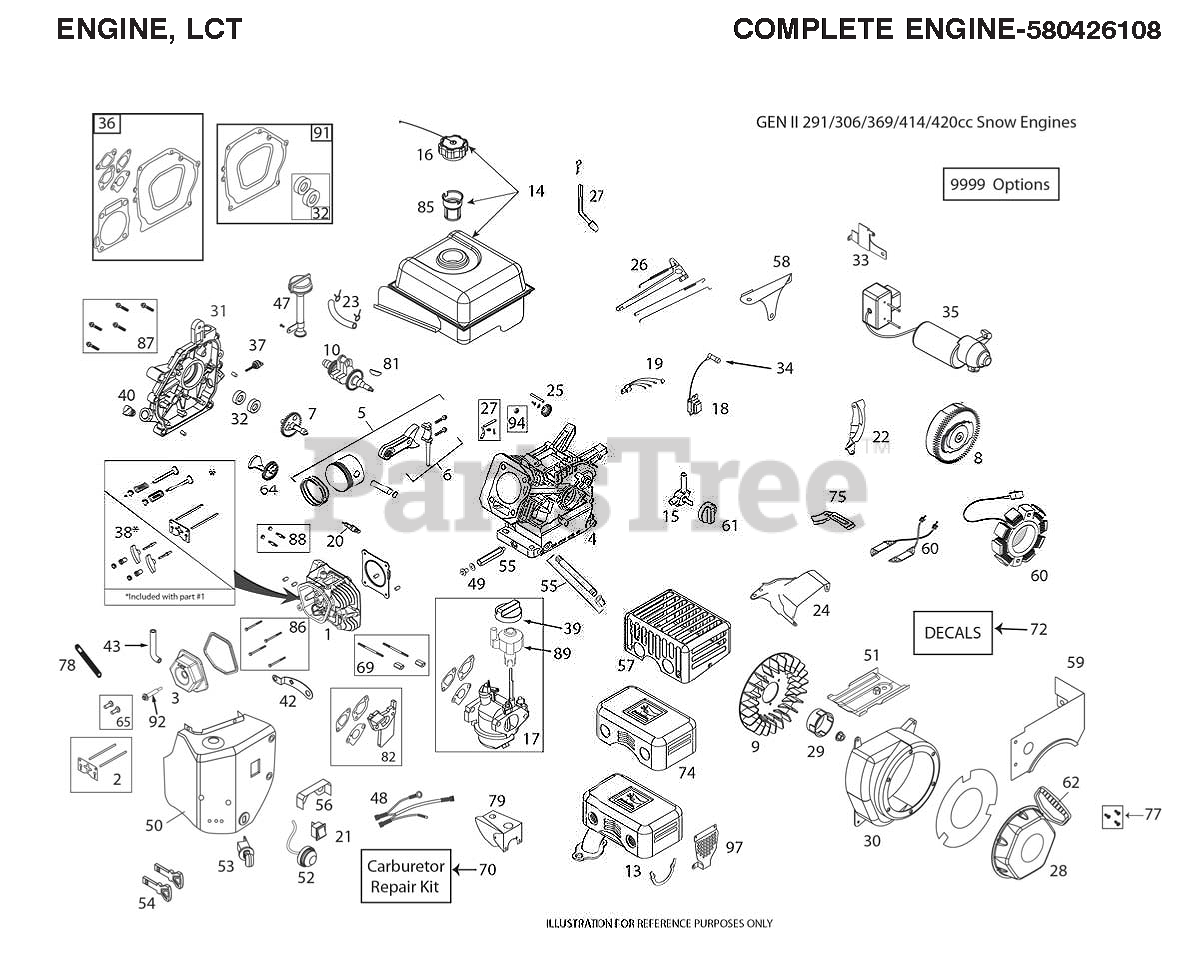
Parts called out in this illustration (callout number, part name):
1	CYLINDER.HEAD.ASSY(SK2911000)
2	PUSH ROD TAPPET KIT
3	VALVE.COVER.LCT.414CC.
4	CYLINDER ASSY SNO.LCT
5	PISTON.AND.ROD.ASSY(SK2911400)
6	CONNECTING ROD ASSY SNO.LCT
7	CAMSHAFT.LCT.291CC
8	FLYWHEEL.EL.ST.SKSNO2401.1
9	FLYWHEEL.FAN
10	CRANKSHAFT
13	MUFFLER ASSY LCT SNO
14	FUEL TANK ASSY - SNOW (291CC)
15	FUEL.PETCOCK.SNOW(SKSN4900)
16	FUEL.TANK.CAP.SNOW(SKSN4301)
17	Husqvarna TBD
18	COIL.IGN.CDI.SKSN2403.1
20	SPARK.PLUG(SK2911550)
21	ON/OFF.SWITCH.SNOW(SKSN4403)
23	FUEL HOSE KIT
24	TOP.SHIELD.LCT.
25	GOVERNOR.GEAR.ASSY(SK2912900)
26	GOVERNOR.ARM.ASSY.(SKSN2502)
27	GOVERNOR.SHAFT.(SK2913100)
28	STARTER RECOIL.291/306CC.LCT
29	STARTER CUP.LCT.291/306CC
30	BLOWER HOUSING.LCT.291/306CC W
31	CRANKCASE.COVER.ASY(SK2913600)
32	OIL.SEAL.KIT(SK2913900)
33	SWITCHBOX BRACKET ES LCT 291 S
34	SPARK.PLUG.BOOT.SNW,SKSN4691.1
35	STARTER, ELECTRIC, 230V
36	ENGINE.GASKET.KIT(SK2914300)
37	DIPSTK.OIL.BLK.LCTSK4143711.1
38	ROCKER ARM KIT
39	CHOKE.KNOW.SNOW(SKSN4500)
40	NONREMVABLE.OIL.PLUG(SK4143715
42	CDI.BOX.BRKT.SNOW(SKSN4402)
43	BREATHER TUBE LCT 291/369/414
47	HIGHOIL.FILL.ASSY.KIT(SKSN4911
48	WIRE.HARNESS(SKSN4406)
50	HEATER.BOX.ASSY.SNOW(SKSN2100)
51	SHIELD.CYLINDER.SNOW(SK4141010
52	PRIMER.BULB.ASSY(SKSN4304)
53	KEY.SWITCH.ASSY.SNOW(SKSN4401)
54	KEY SET(2 KEYS) SKSN0407.1
55	OIL PIPE DRAIN EXTENDED.LCT SK
56	SHIELD.VAPOR(SKSN4606)
57	MUFFLER GUARD.CE.LCT
58	GOVERNOR.LINK.SHIELD(SKSN2501)
59	FUEL TANK SKIRT.LCT.291/306CC
60	ALTERN.60WATT.SKSN2402.1
61	FUEL KNOB-SNOW
62	HANDLE.RECOIL.DELUXE.LCT
65	TAPPET KIT.LCT.SK2911005.1
69	STUD.CARB.MOUTING.KIT.291CC
70	CARBURETTOR REPAIR KIT 291CC/4
74	MUFFLER SHIELD
75	WIRE GUARD
77	BOLT.KIT.RECOIL.LCT.ALL.ENGINE
79	SHIELD CARBURRETOR COVER 414
81	KEYS.FLYWHEEL.136/291CC.5PACK
82	SPACER.CARBURETOR.291CC.LCT
85	STRAINER.FUEL.TANK.LCT.208CC
86	KIT.BOLT.CYLINDER.HEAD.(4PC)
87	KIT.7-BOLT.CRANKCASE.CVR.291CC
88	STUD.MUFFLER.KIT.LCT
89	KNOB LCT.SKSN5325.1 SPEED
91	GASKET KIT CRANKSHAFT.LCT
92	CENTER VALVE COVER BOLT
9999	KIT.BOLT.LCT.SK9990.1
9999	HIGH.ALTITUDE.JET.6000FT ANDUP
